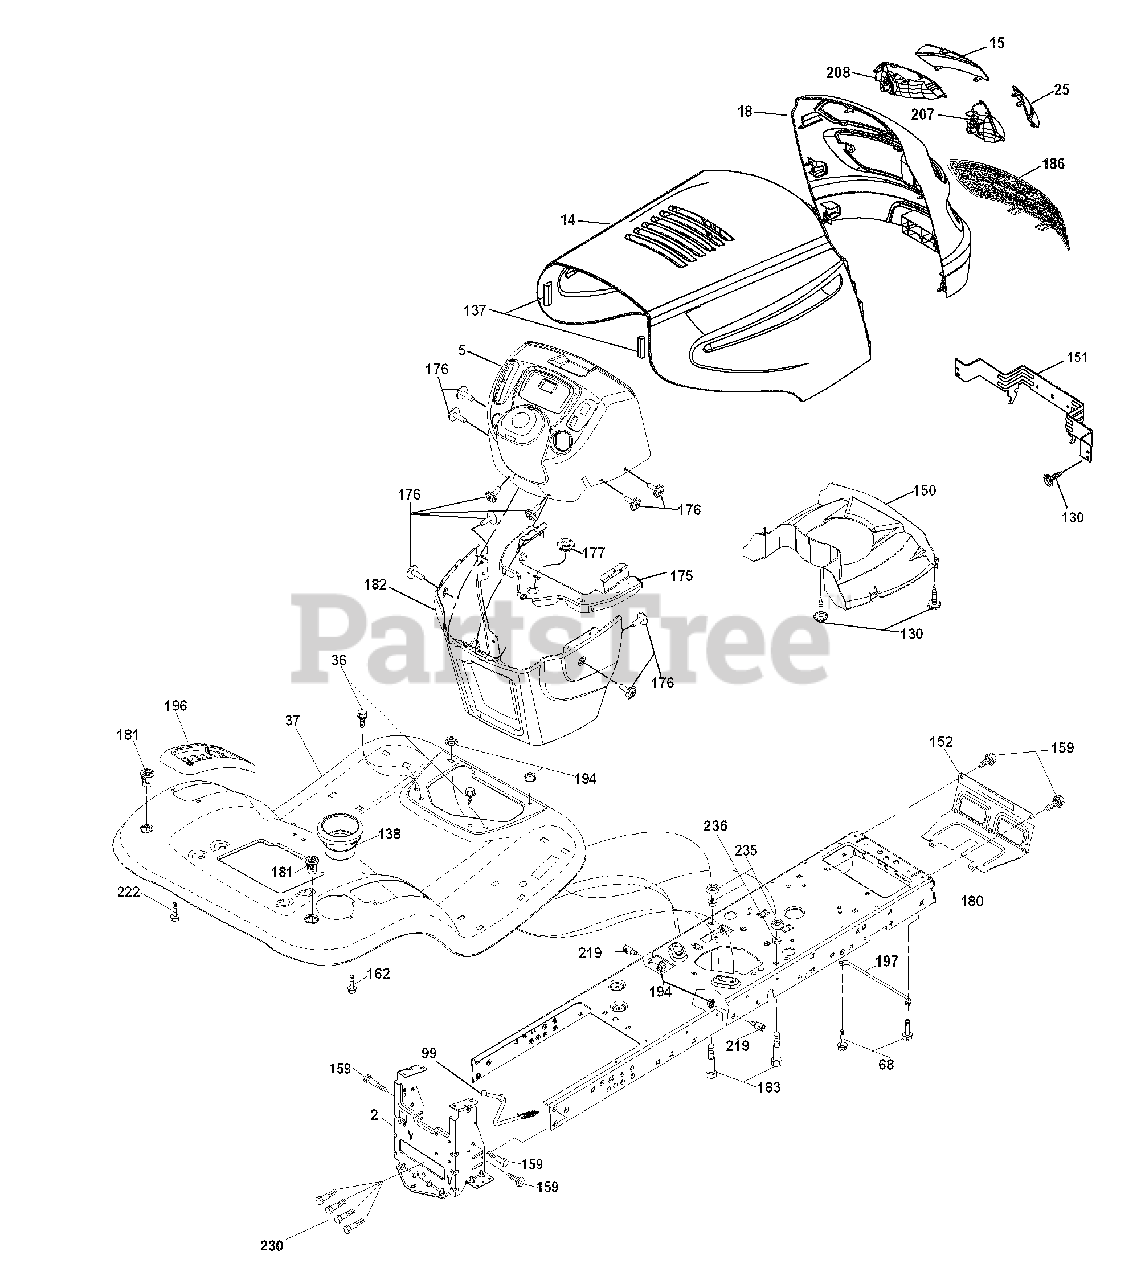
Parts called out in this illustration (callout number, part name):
2	Drawbar
5	Dash
14	Hood
15	Lens Grille LH
18	Grille
25	Lens Grille RH
36	Screw 5/16-18 x 3/4
68	Screw Thdrol 5/16-18 x 1/2
99	Rod Bypass
130	Screw 10 x 3/4 Single Lead-Hex
137	Bumper Hood
138	Cupholder
150	Duct Heat Hood
151	Bracket Pivot
152	Shield Browning/Debris
159	Screw Hexwsh Thdrol 3/8-16 x 3/4
162	Screw Hex Wsh Hi-Lo 1/4 x 1/2
175	Crossmember
176	Screw 10-24 x 5/8 Wshd Qdrx
177	Bushing Steering
181	Bushing Mtg. Fender Crgo.
182	Dash Lower
183	Bolt Fin Hex 5/16-18 x 1-1/4
186	Insert Grille
194	Nut Lock Hex Flange 5/16-18
196	Console Asm. Deck Lift
197	Rod Pivot Chassis
207	Bezel Grille RH
208	Bezel Grille LH
219	Stud Fastener
222	Screw Thd Roll 1/4-20 x 5/8
230	Bolt Shoulder 5/16-18
235	Spacer Fender
236	Nut center Lock 5/16-18
